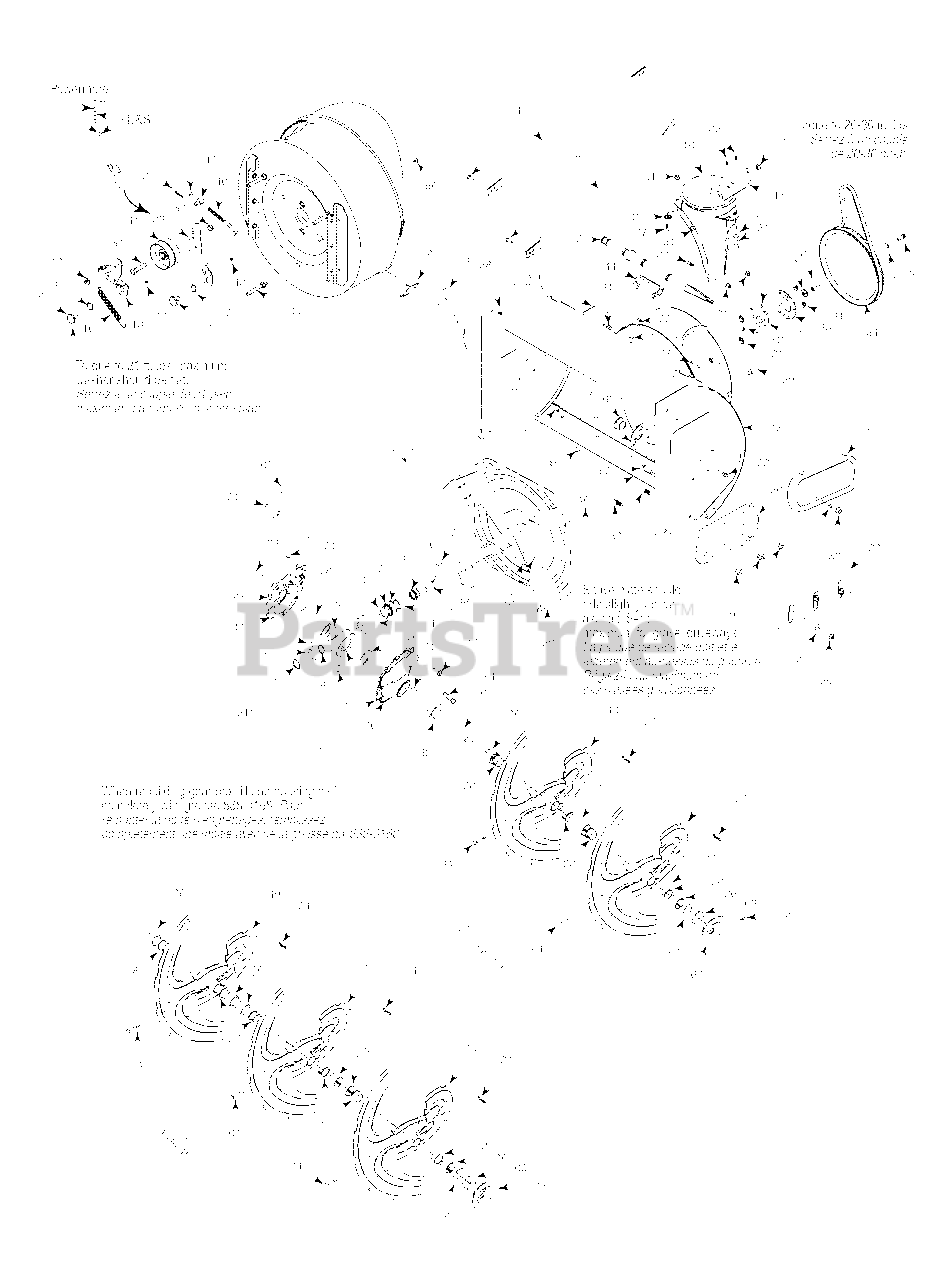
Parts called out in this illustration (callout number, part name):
1	Flat Washer .349 ID x .879 OD x .063
2	Hex Jam Nut 5/16-18 Gr. 5
3	Flat Washer .760 ID x 1.49 OD
4	Flat Washer .34 x 1.5 x .150
5	Handle Knob Assembly
6	Hex Screw 5/16-24 x .875 Gr. 8 Lock
7	Hex Hd Cap Scr. 5/16-18 x .75 Gr. 5
8	Flat Washer .385 x .870 x .092
9	Shell Alvania Grease (3 oz.)
10	Extension Spring .470 Dia. x 4.75
11	Ultra Grey Loctite #5699
12	Flat Washer .344 ID x .75 OD x .120
13	Brake Bracket Ass’y (900 Series)
14	Plastic Bushing .380 ID
16	Chute Adapter
17	Reversible Slide Shoe (Plastic)
18	Screw, 5/16-18 x .5
19	Adjustment Ferrule
20	Support Tubing RH (w/plastic panel)
20	Support Tubing LH (w/plastic panel)
21	Push-on Nut .25 diam
22	Deluxe Reversible Slide Shoe
23	Hex TT Screw 5/16-18 x .75
24	Bow Tie Cotter Pin
26	Spacer 1.5 x 1.0 ID x 1.0" Lg.
27	Spacer 1.5 x 1.0 ID x 2.5" Lg.
28	Flange Bushing 1.05 ID x 1.16 OD
30	Self-Aligning Bearing .875 ID
31	Hex Flg. L-Nut 5/16-18 Gr. F Nylon
32	Flat Washer 1.010 x 1.88 x .060
33	Bearing Housing
34	Pulley .5 ID x 10 OD
35	Shoulder Screw .625 Dia x .170
36	Auger Idler Bracket
37	Wave Washer .625 ID x .885 OD x .015
38	Carriage Bolt 5/16-18 x .75
39	Screw 5/16-18 x .43 (w/stud)
40	Auger Idler Rod
41	Flat Idler Pulley
42	Cleanout Tool
44	Cleanout Tool Mount
45	Auger Housing 28" Orange
45	Auger Housing 30" Orange
45	Auger Housing 33" Orange
46	Shave Plate 28" Orange
46	Shave Plate 30" Orange
46	Shave Plate 33" Orange
47	Support Tubing (w/steel panel)
48	Arctic Grease
49	LH Auger - Black
49	RH Auger - Black
51	Worm Gear Box Ass’y (w/o grease fitting)
51	Worm Gear Box Ass’y (w/ grease fitting)
52	Carriage Bolt 3/8-16 x 1.00" (w/steel shoe)
52	Carriage Bolt 3/8-16 x 1.25" (w/plastic shoe )
53	Carriage Bolt 3/8-16 x .75" (w/steel shoe)
53	Carriage Bolt 3/8-16 x 1.00" (w/plastic shoe)
54	Hex Hd. Cap Scr 3/8-16 x 1.75 Gr. 5
55	Grease Fitting
56	Hex Flange L-Nut 3/8-16 Gr. F Nylon
58	Spring Spirol Pin Heavy - 5/16 dia x 1.7
59	Blower Fan Ass’y Complete
60	Gear Housing Support Bracket
61	Barbed Plug
63	Auger Shaft 28"
63	Auger Shaft 30"
63	Auger Shaft 33"
64	Shear Pin 5/16-18 x 1.75
65	Gear Housing Half - RH
66	Flange Bearing
67	#9 HI-Pro Key 3/16 x 3/4 Dia HT
68	Auger Drive Shaft
69	Snap Ring for .875 dia. shaft
70	Oil seal for .875 ID Garlock (76 x 6133)
71	Sleeve Bearing .875 ID
72	Thrust Bearing .88 ID x 1.44 OD x .078
73	Flat Washer .88 ID x 1.4 OD x .125
74	Worm Gear LH Double Thread
75	Spacer
76	Flat Washer 1.5 ID x 2.0 OD x .03
77	Worm Gear LH Double Thread (Bronze)
78	Worm Gear Shaft
79	#91 Woodruff Key 1/4 x 3/4 Dia.
80	Gear Housing Half LH
80	Gear Housing Half LH (w/grease fitting hole)
81	#91 Woodruff Key 1/4 x 3/4 Dia.
82	Low Temperature grease
83	Pulley Adapter .75 Dia. w/pins
84	Hex Hd. Cap Scr. 5/16-18 x 1.0 Gr. 5
85	Carriage Bolt 5/16-18 x 1.00" Lg
05845C-0665	HOUSING:BEARING - YARDMAN GREEN (0665)
